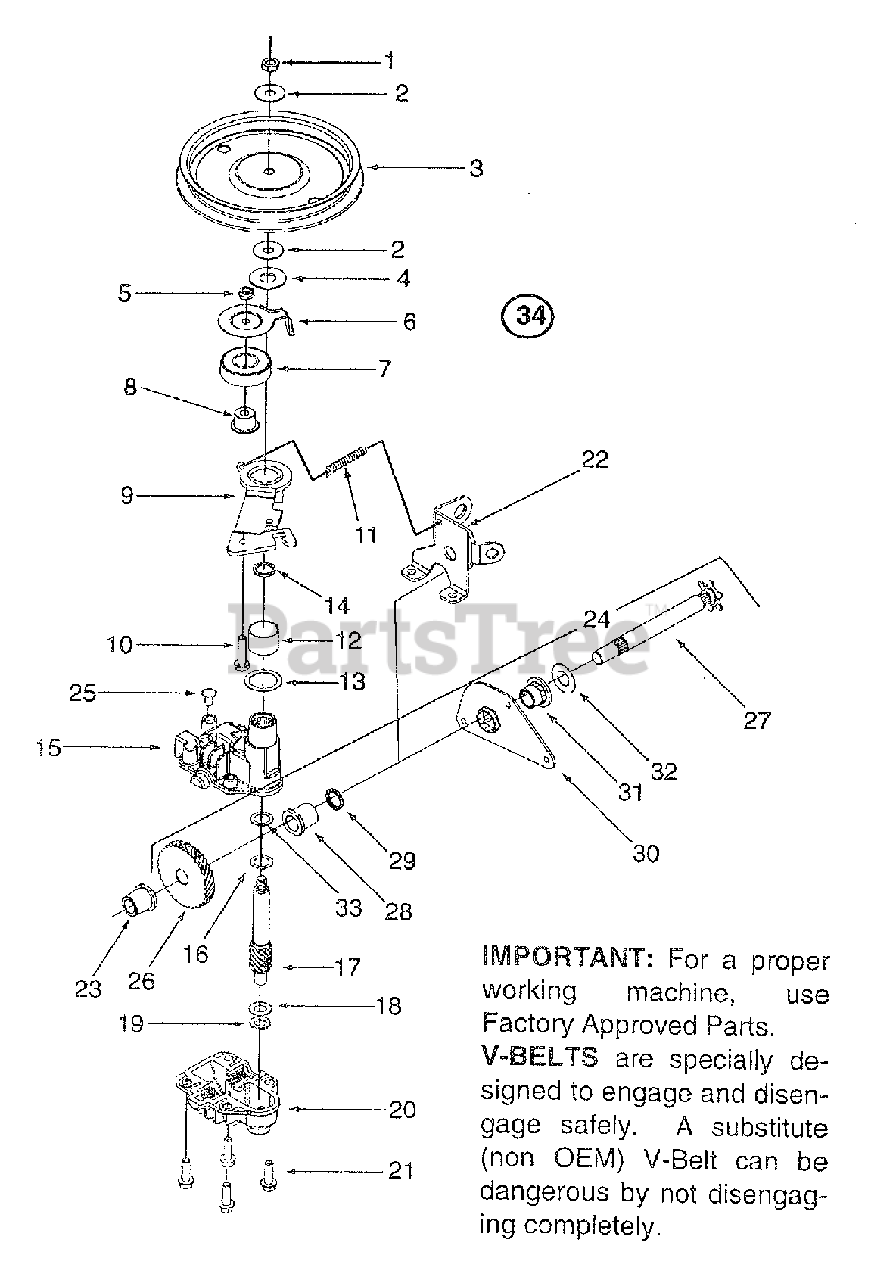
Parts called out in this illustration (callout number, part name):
1	Hex Jam Nut 5/16-24
2	Bell Washer .325 x .930
4	Flat Washer .510 x 1.120
5	Hex Jam Nut 1/4-28
6	Belt Keeper
7	Bearing
8	Flange Spacer
9	Idler Bracket Assembly
10	Hex Cap Screw 1/4-28 x 1.0
11	Extension Spring
12	Bearing Sleeve
13	Flat Washer .885 x 1.45
14	Oil Seal
15	Upper Housing Assembly
16	Thrust Washer .504 x .70
17	Pinion Shaft 10T
18	Thrust Washer 3/8 x .70
19	Thrust Washer .388 x .625
20	Lower Housing Assembly
21	Hex Screw 1/2-20 x .75
24	Shaft Assembly
27	Output Shaft 6T
28	Flange Bearing
29	Oil Seal
30	Pivot Bracket
31	Flange Bearing
32	Flat Washer .508 ID x 1.0
34	Transmission Assy. Complete
